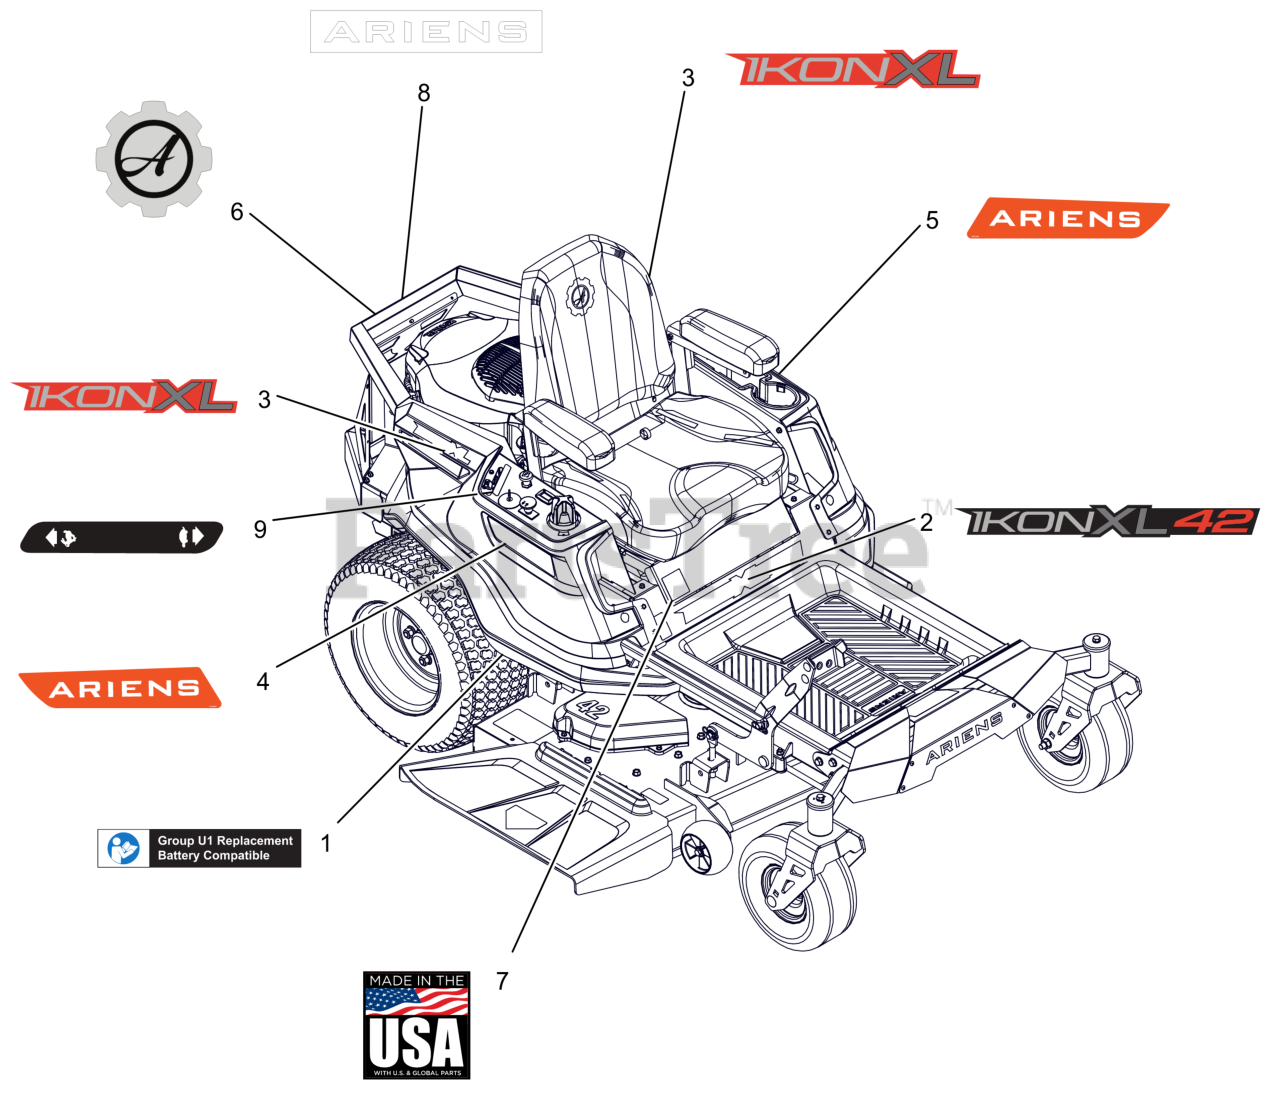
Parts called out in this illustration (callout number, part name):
1	DECAL, U1 BATTERY REPLACEMENT
2	DECAL, IKON-XL 42"
3	DECAL, IKON-XL
4	DECAL, FENDER RH
5	DECAL, FENDER LH
6	DECAL, ARIENS-GEAR BADGE -THK
7	DECAL, MADE IN USA
8	DECAL - ARIENS 9.625"
9	DECAL, DASH DECAL
